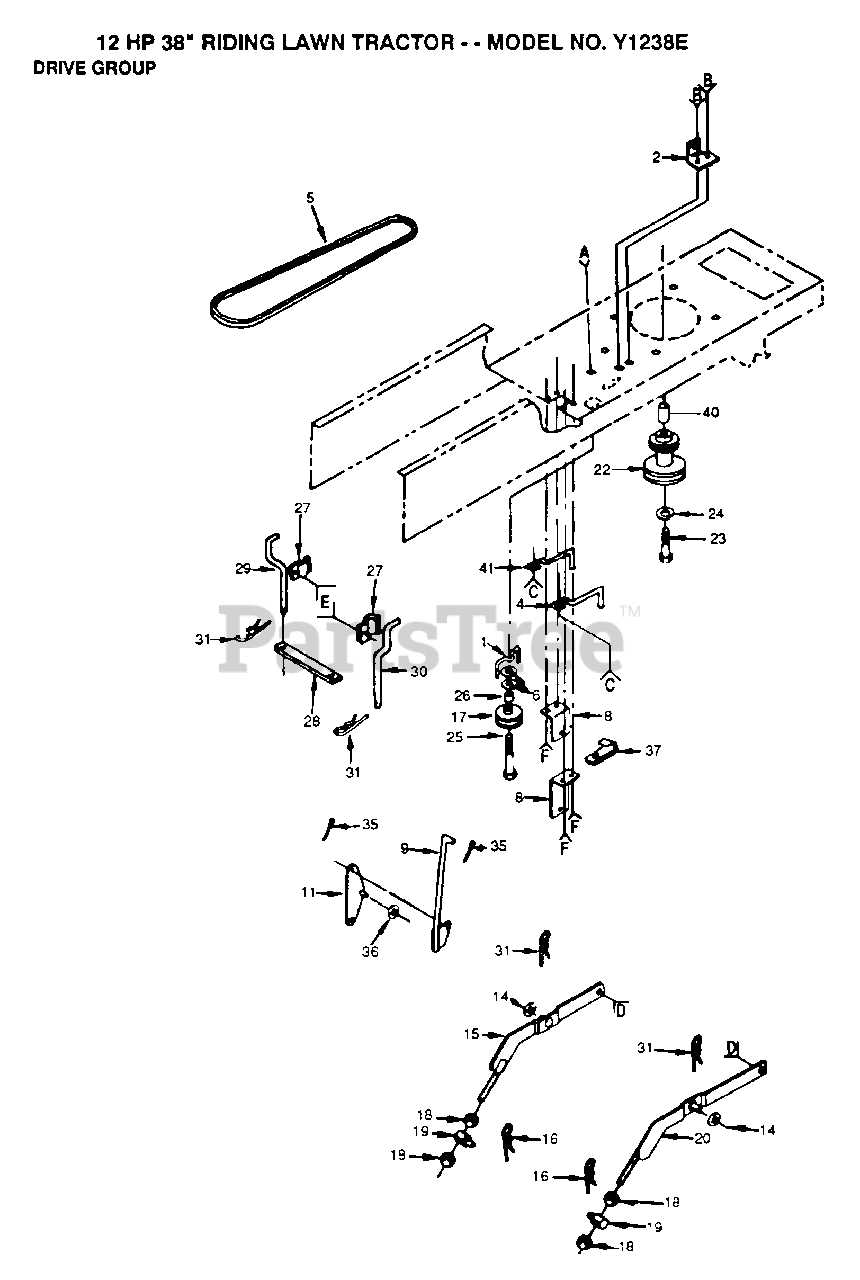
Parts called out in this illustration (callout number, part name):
1	BELT KEEPER LT
2	BRACKET LT
4	"KEEPER,BLT ENG LT"
5	BELT-V.90.0.GD.DR
6	WASHER
8	"BRKT,BELLCRAN T"
9	ROD ASSEM YT
11	"T, BELLCRANK"
15	LH SUSP ARM ASM
16	SPRING H
17	PULLEY.IDLER.FLAT
18	NUT
20	RH SUSP ARM ASM
23	BOLT
24	LOCKWASHER
25	BOLT
26	SPACER T
27	CLAMP LT
28	STRAP LOCATOR
29	KEEPER BELT LH
30	KEEPER BELTRH
31	SPRING.RETAINER
35	COTTER PIN
36	WASHER
37	INSUL CLIP T
40	SPACER T
41	KEEPER BELT ENGLH
